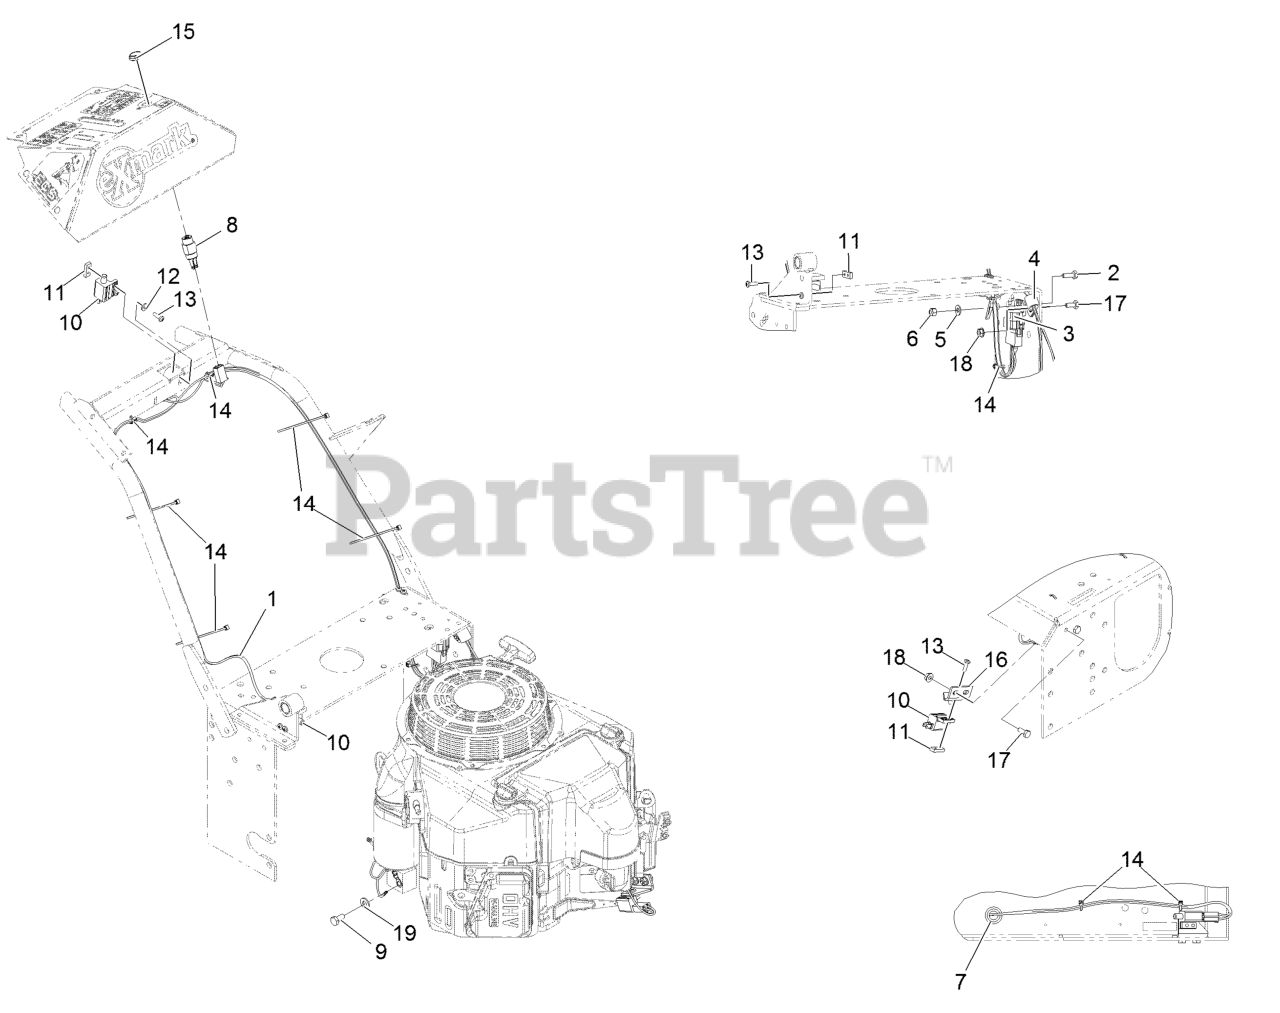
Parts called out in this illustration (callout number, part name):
1	HARNESS-WIRING
2	SCREW-HH
3	MODULE-INTERLOCK
4	CLIP-LOOM
5	WASHER-FLAT
6	NUT-LOCK, NI
7	GROMMET
8	SWITCH & KEY (INCLUDES NU
9	SCREW-HH
10	SWITCH-OPEN, NORMALLY
11	PLATE-TAPPED
12	WASHER-FLAT
13	SCREW-PPH
14	TIE-CABLE
15	NUT-SWITCH, IGNITION
16	BRACKET-SWITCH, BLADE
17	SCREW-HH
19	WASHER-PLAIN
